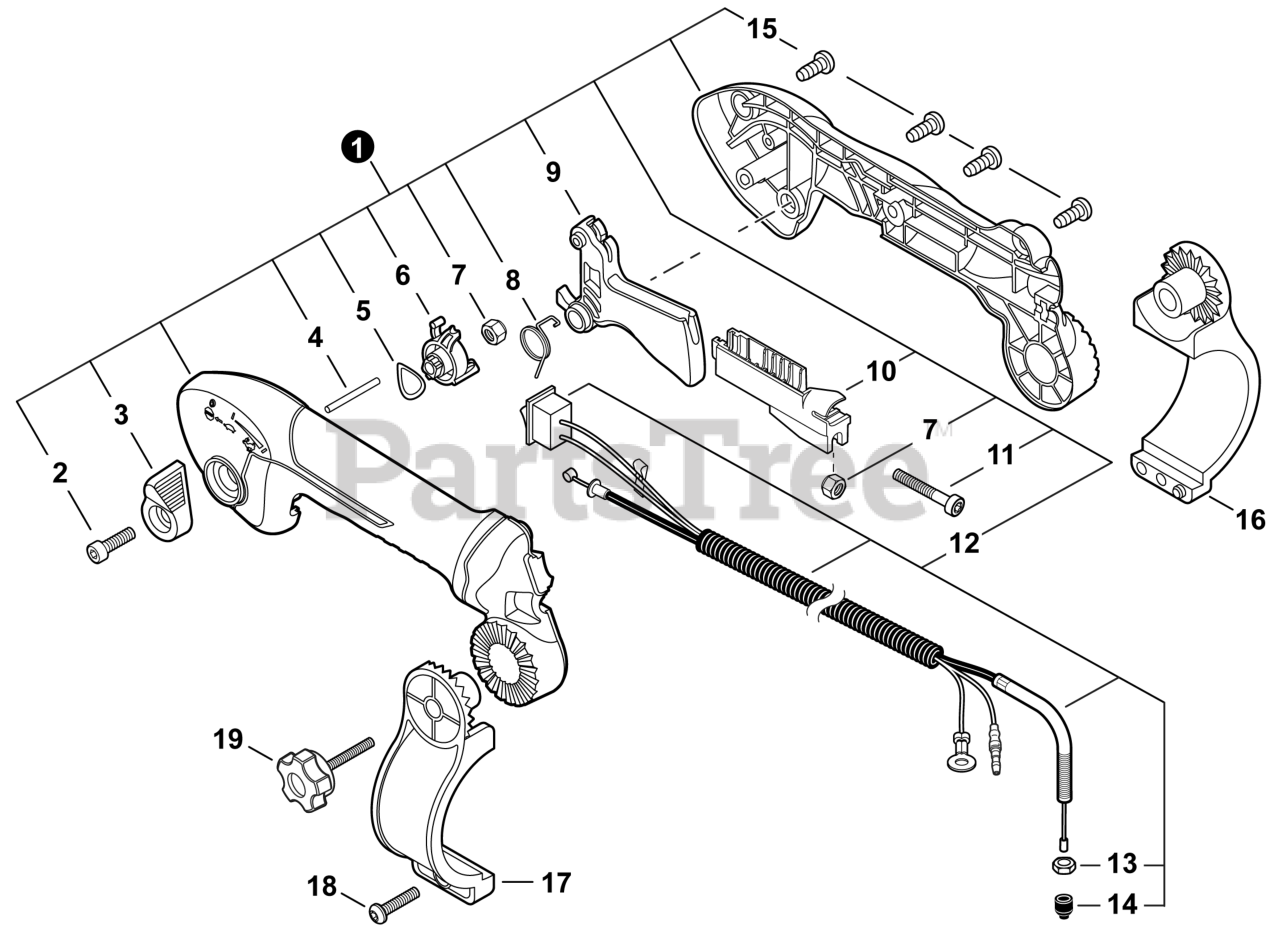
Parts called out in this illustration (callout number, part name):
1	THROTTLE CONTROL KIT - TUBE MOUNT
2	BOLT, TORX 5x20
3	LEVER, THROTTLE
4	PIN 3x32
5	WASHER, WAVE 12
6	CONTROL, THROTTLE
7	NUT, LOCK M5
8	SPRING, TORSION
9	TRIGGER, THROTTLE
10	CONNECTOR, CABLE
11	BOLT, TORX 5x30
12	CABLE ASSY, CONTROL
13	NUT, HEX M6
14	CAP, DUST
15	BOLT, TORX 5x16
16	BRACKET, RIGHT
17	BRACKET, LEFT
18	BOLT, TORX 5x20
19	KNOB, SCREW
